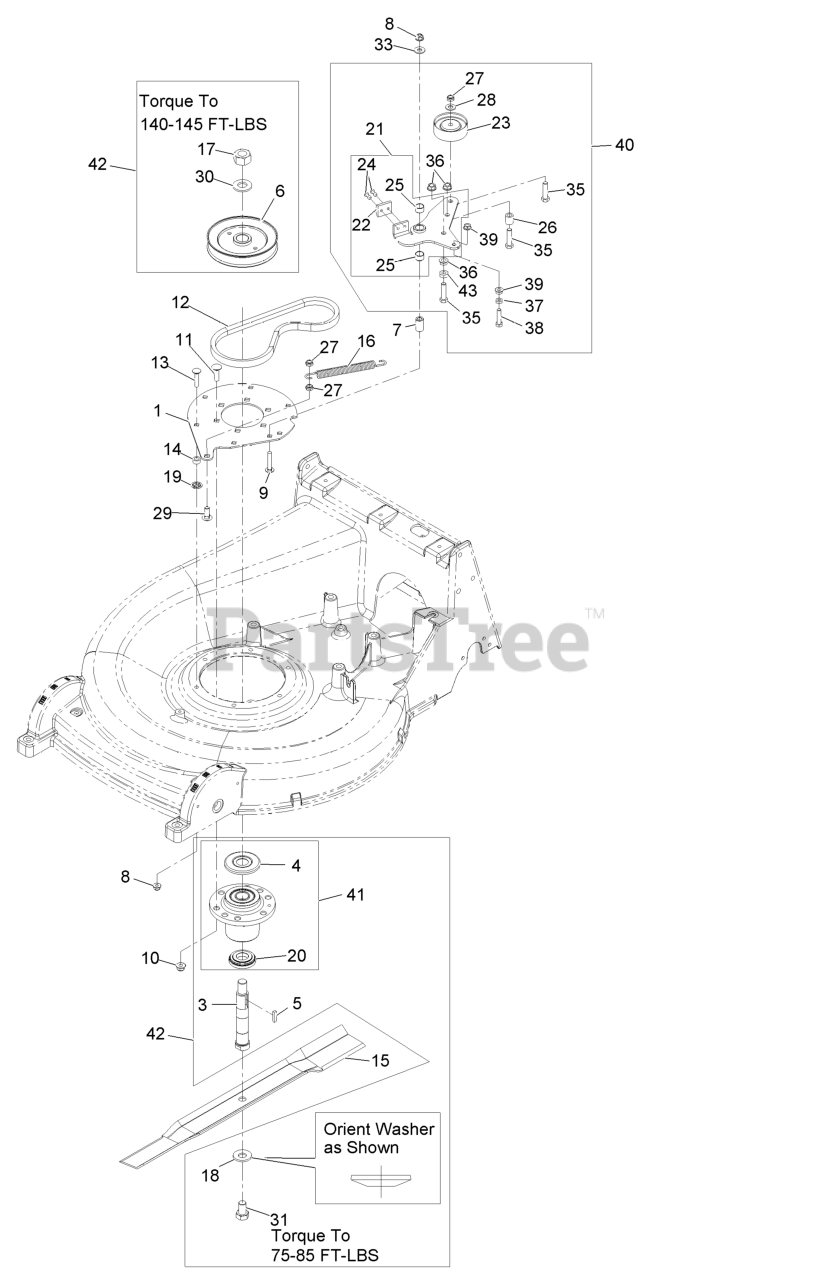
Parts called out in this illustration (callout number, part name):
1	PLATE-ADAPTER, HOUSING
3	SHAFT-SPINDLE
4	GUARD-BEARING, TOP
5	KEY-RECTANGLE
6	SHEAVE-SPLIT, STEEL (W/HU
7	BUSHING-ARM, IDLER
8	NUT-HF, NI
9	SCREW-CARR
10	NUT-HF, NI
11	Bolt-Carriage 3/8-16 X 1 1/4
12	BELT
13	BOLT-CARR
14	SPACER
15	BLADE, METRO 26
16	SPRING-BRAKE
18	WASHER-SPRING
19	RING-RETAINING
20	SPACER-GUARD, BOTTOM
21	ASM,IDLER ARM W/BSHGS
22	PAD-BRAKE
23	PULLEY-IDLER
24	RIVET-POP
25	BEARING
26	BUSHING-LEVER, LIFT
28	WASHER-FLAT
29	SCREW-CARR
31	SCREW-CAP
33	WASHER-FLAT
35	SCREW-HH
36	NUT-HHF, WHIZ
37	NUT-JAM
38	SCREW-HH
40	IDLER ARM ASM
41	KIT, CUTTER HOUSING
42	ASM,CUTTER HOUSING COMPLE
43	NUT-JAM
